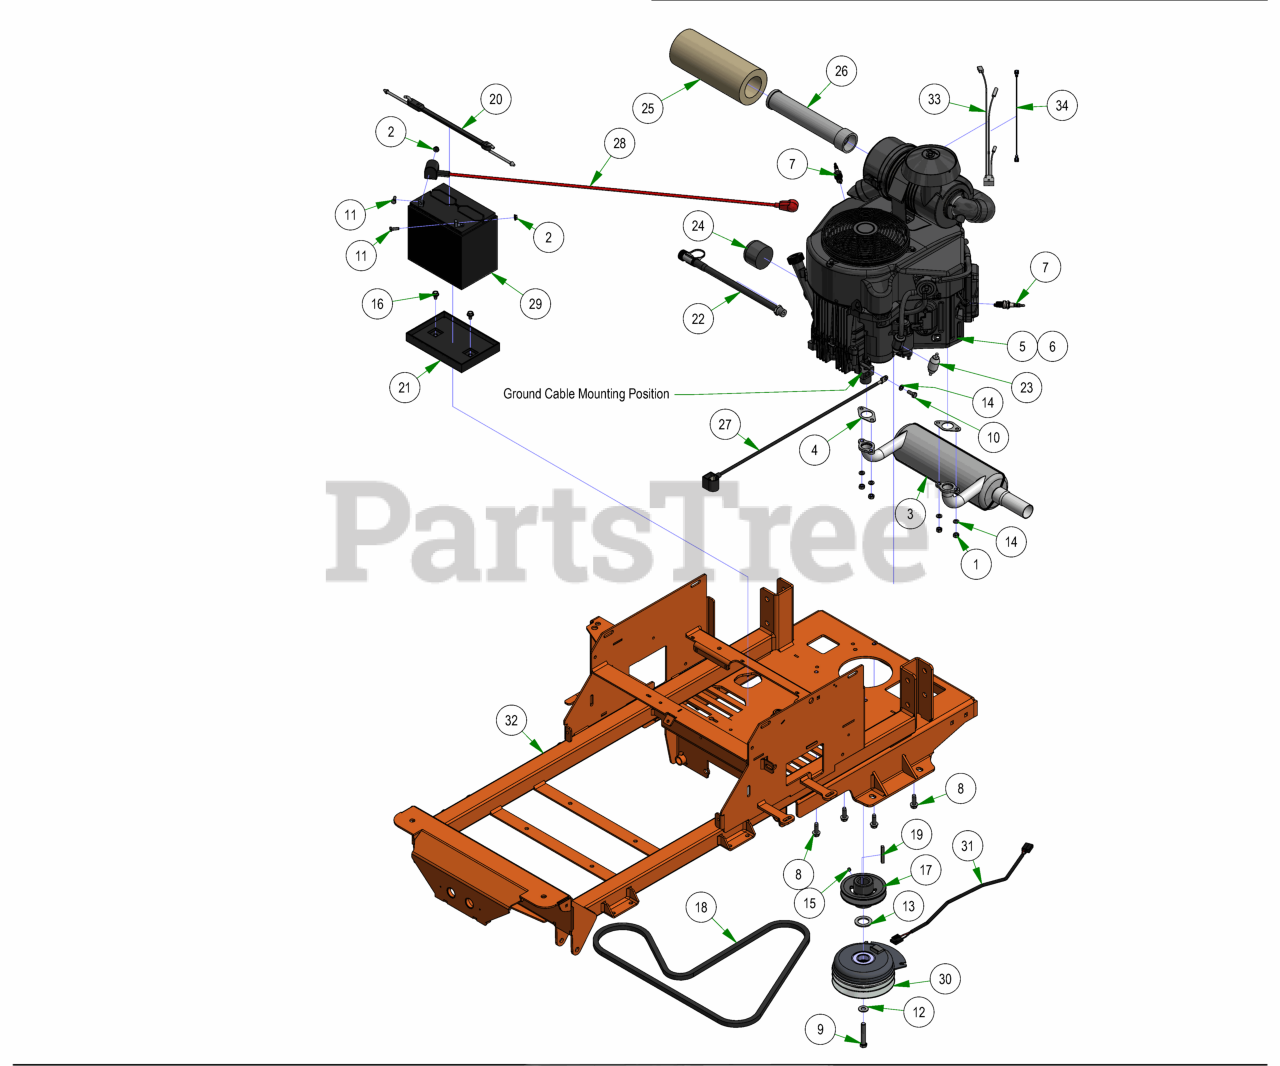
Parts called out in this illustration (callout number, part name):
1	M8-1.25 DIN 934 HEX NUT (CL.8) ZINC
2	1/4-20 HEX SERRATED FLANGE NUT HARD/ZINC
3	Kawasaki Muffler 1251
4	Exhaust Gasket
5	FX691 Kawasaki-2016 Compact Outlaw
7	Spark Plug - Kawasaki
8	3/8-16 X 1-1/8 HEX WASHER UNSLOT SERRATED (TRI-LOB) TRS ZINC YELLOW
9	7/16-20 X 2.5" HEX Bolt GR.8 W/Patch
10	M8-1.25 X 20MM DIN 933 HEX TAP BOLT (CL 8.8) ZINC
11	1/4-20 X 3/4 HEX CAP SCREW (GR.5) ZINC
12	3/8 FLAT WASHER USS (1" OD) ZINC
13	1.140 ID X 1.750 OD X .132 THICK FLAT WASHER PLAIN
14	5/16 SPLIT LOCKWASHER ZINC
15	5/16-24 X 1/4 SOCKET SET SCREW (CUP PT) PLAIN
16	5/16-18 X 1/2 HWH unslot (F) tcs zinc
17	4 3/4 Motor Pulley
18	75.8" Pump Belt
19	1/4 X 2 SQ MACHINERY KEY 1018 STL PLAIN
20	2023 Rubber Battery Hold Down Strap
21	Battery Tray
22	Kawasaki Oil Drain
23	Universal Inline Fuel Filter
24	Oil Filter
25	Canister Air Filter- Outer
26	Canister Air Filter- Inner
27	24 inch Black Cable – MZ/ZT
28	36" Red Battery Cable
29	SP-35 Battery
31	Clutch Pigtail
32	2025 Maverick Frame
33	Harness Adaptor
34	Compact Outlaw/Honda Starter Jumper Wire
